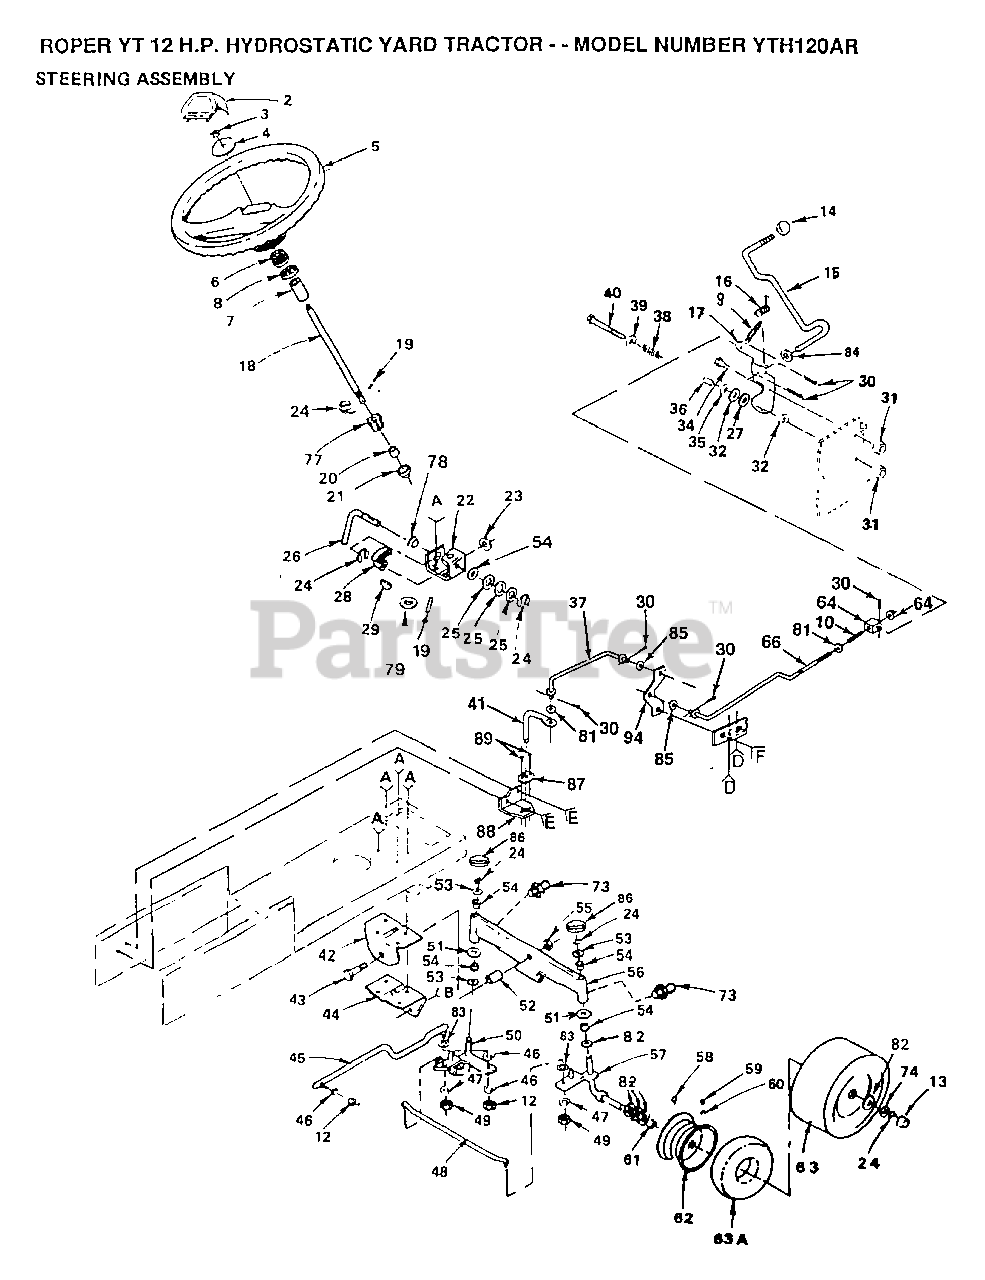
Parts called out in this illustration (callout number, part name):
2	INSERT STEERING
4	WASHER
6	ADAPTER LT
9	SPRING.RETAINER
10	SPRING GTV
13	HUB CAP
14	KNOB.DUCKHEAD.1/2
15	ROD.YTH
16	SPRING TORSION
17	BRKT CONTROL HYT
18	STEERING SHAFT T
20	SHAFT SPACER LT
21	BUSHING
23	WASHER D
24	RING
25	WASHER .T
26	ROD STEERING T
27	WASHER HYT
28	GEAR.SECTOR.HYT
29	KEY-WOODRUFF LT
30	COTTER PIN
32	WASHER FRIC HYT
34	BOLT HYT
35	WASHER D
36	SPACER HYT
37	LINK CONTROL
38	SPRING HYT
39	WASHER
40	BOLT - HEX 3/8 - 16 X 3
41	ARM ASM PUMP
42	SUPPORT-SADDL T
43	BOLT LT
44	SUPPORT.SADDLE.FT
45	LINK-DRAG LT
46	LOCKWASHER
47	LOCKWASHER
48	ROD TIE
49	NUT.LOCK.5/16-24
50	SPINDLE-LH LT
51	WASHER
52	BEARING
53	WASHER .T
54	COL. SRTG. BEAR.
55	"NUT-LOC,FLANGE LT"
56	FRONT AXLE
58	FITTING LT
59	VALVE STEM LT
60	VALVE CAP
61	"FLANGE, BEARING"
63A	TUBE.5.3/4.5/6
64	NUT
66	ROD ADJ CONTROL
73	ZERK M
74	WASHER
77	GEAR PINION T
78	NYLINER T
81	WASHER T
83	WASHER M
84	WASHER
85	WASHER T
86	CAP
87	GUIDE CONTROL
88	BRKT
89	SCREW
94	BELLCRANK
